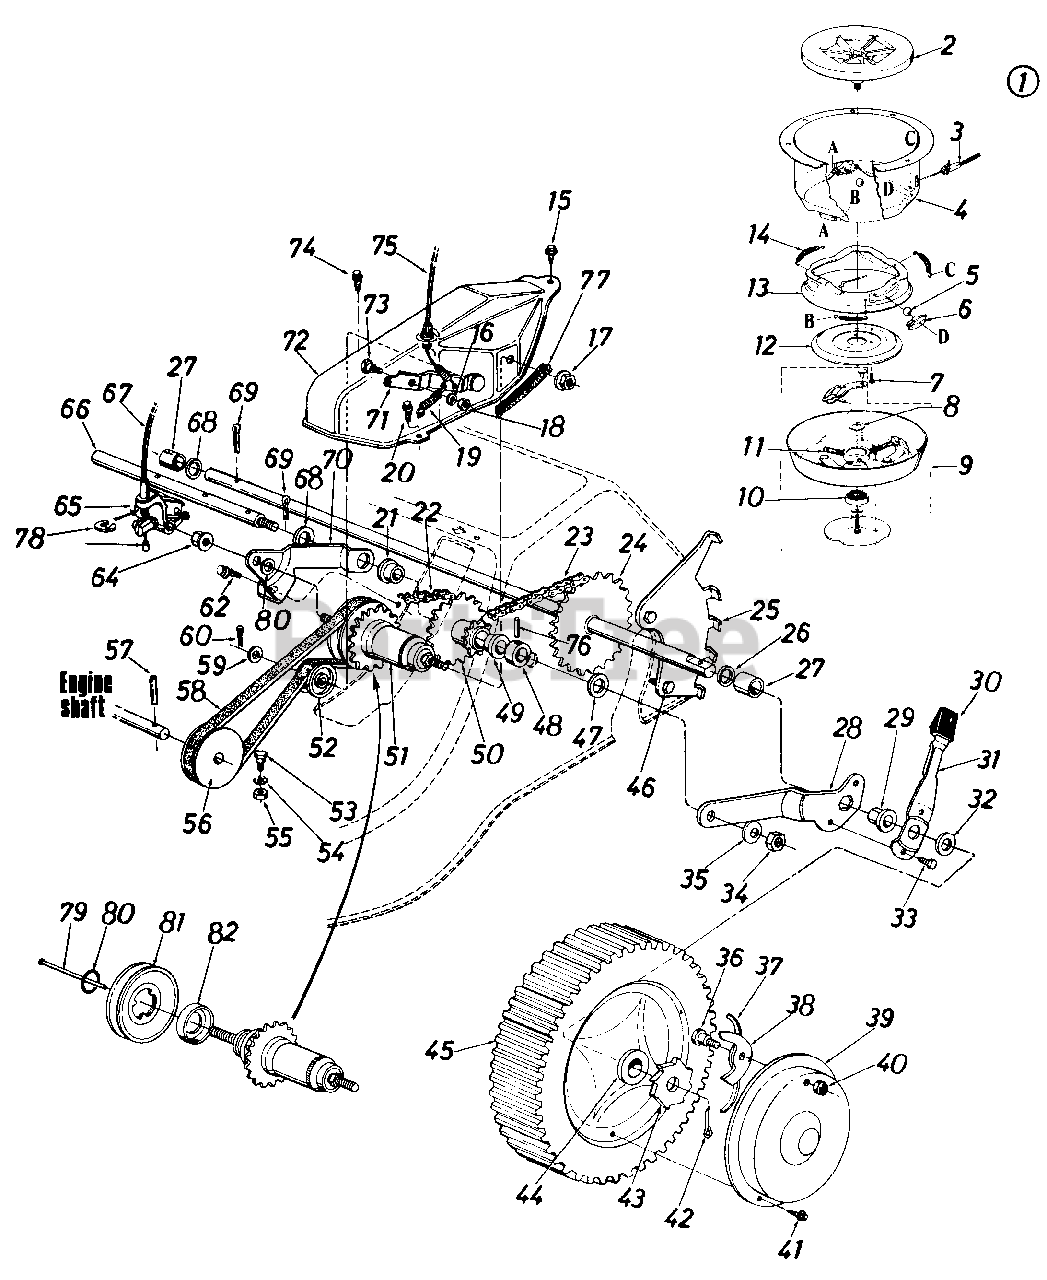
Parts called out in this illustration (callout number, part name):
1	Blade/Brake Clutch Ass'y.
2	Fan Adapter
3	BBC-Clutch Cable-46"
4	Clutch Housing
5	Steel Ball .500" Dia.
6	Ball Block
7	Hex Wash. TT-Tap Cl-Scr. 1/4 -20 x .75" Lg.
8	Fl-Wash. .690" I.D. x 1.060" O.D.
9	Clutch Blade Hsg. Ass'y.
10	Ball Brg. .669" I.D. x 1.574" O.D
11	Compression Spring .32" O.D. x 2.00" Lg.
12	Clutching Cone
13	Brake Cup Cone
14	Extension Spring-1.75" Lg.
15	Hex Drilling Scr. #10 x .50"
16	L-Wash. 1/4" I.D.*
17	Hex Nut 3/8-24 Thd.
18	Hex Nut 1/4-20 Thd.
19	Extension Spring-1.12" Lg.
20	Hex Wash. S-Tap Scr. 1/4-20 x .50" Lg.
21	Flg. Brg. .506" I.D.-Plastic
22	#48 Chain 1/2" Pitch x 38 Links
23	#48 Chain 1/2" Pitch x 32 Links
24	Rear Shaft Ass'y.-20.75"
25	Index Plate Rear-L.H.
26	Fl-Wash. .510" I.D. x 1.0"
27	Spacer.740" I.D.
28	Pivot Brkt.-L.H.
29	Hex Flange Brg. .506" I . D .-Plastic
30	Spring Lever Knob
31	Spring Lever
32	Fl-Wash. .531" I.D. x .930"
33	Hex B-Tap Scr. 1/4 x .38"
34	Hex Jam Nut 3/8-16 Thd.
35	Bell-Wash. .400" I.D. x .88"
36	Shld. Bolt .342" Dia. x .268
37	Spring-Nylon
38	Pawl
39	Hub Cap
40	Hex Ins. L-Nut 1/4-20 Thd.
41	Pan Hd. Tap Scr. #12 x .50" Lg.
42	Cotter Pin 1/8" Dia. x 1.0"
43	Ratchet Wheel 1.62n O.D.
44	Fl-Ball Brg. 1/2" I.D.
45	Wheel Ass'y. Comp. 8 x 1.75
46	Hex L-Wash. Hd. AB-Tap Scr. 1/4 x .62" Lg.
47	Bell-Wash. .40" I.D. x 1.13"
48	Spacer. 505" I.D.
49	Flg. Brg. .506" I.D. Plastic
50	9 and 21 Tooth Sprocket Ass'y.
51	Shimano 3-Sp. Hub w/18 Tooth Sprocket
52	Fl-Idler Plastic 1.62" Dia.
53	Shld. Bolt .437" Dia. x .180
54	L-Wash. 5/16" I.D.
55	Hex Nut 5/16-18 Thd.
56	1/2" "V"-Engine Pulley .50" I.D. x 2.80" O.D.
57	Spring Pin Spir. 3/16" Dia. x 1.50" Lg.
58	"V"-Belt
59	Fl-Wash. .531" I.D. x .930"
60	Cotter Pin 1/8" Dia. x 1.0"
62	Hex Wash. Hd. Tap Scr. 5/16-18 x .75" Lg.
64	Hex Nut 3/8-24 Thd.
65	Shimano 3-Sp. Shift Bell Crank
66	Pulley Shaft 10" Lg.
67	Shimano 3-Sp. Solid Shift Cable
68	Fl-Wash. .531" I.D. x .930"
69	Cotter Pin 3/32" Dia. x 1.0"
70	3-Sp. Hub Bracket
71	Idler Bracket Ass'y.
72	3-Sp. Belt Cove
73	Shld. Bolt .375" Dia. x .181
74	Hex TT-Tap Scr. 1/4-20 x .75" Lg.
75	S.P. Cable-53" Lg.-Blue
76	Spring Pin Spir. 3/16" Dia. x 1.0" Lg.
77	Trim Strip
78	Snap Ring
79	Shifting Pin
80	Pulley Snap Ring
81	1/2" V-Pulley 1.375" I.D. x 3.25" O.D.
82	Shimano 3-Sp. Dust Cover
